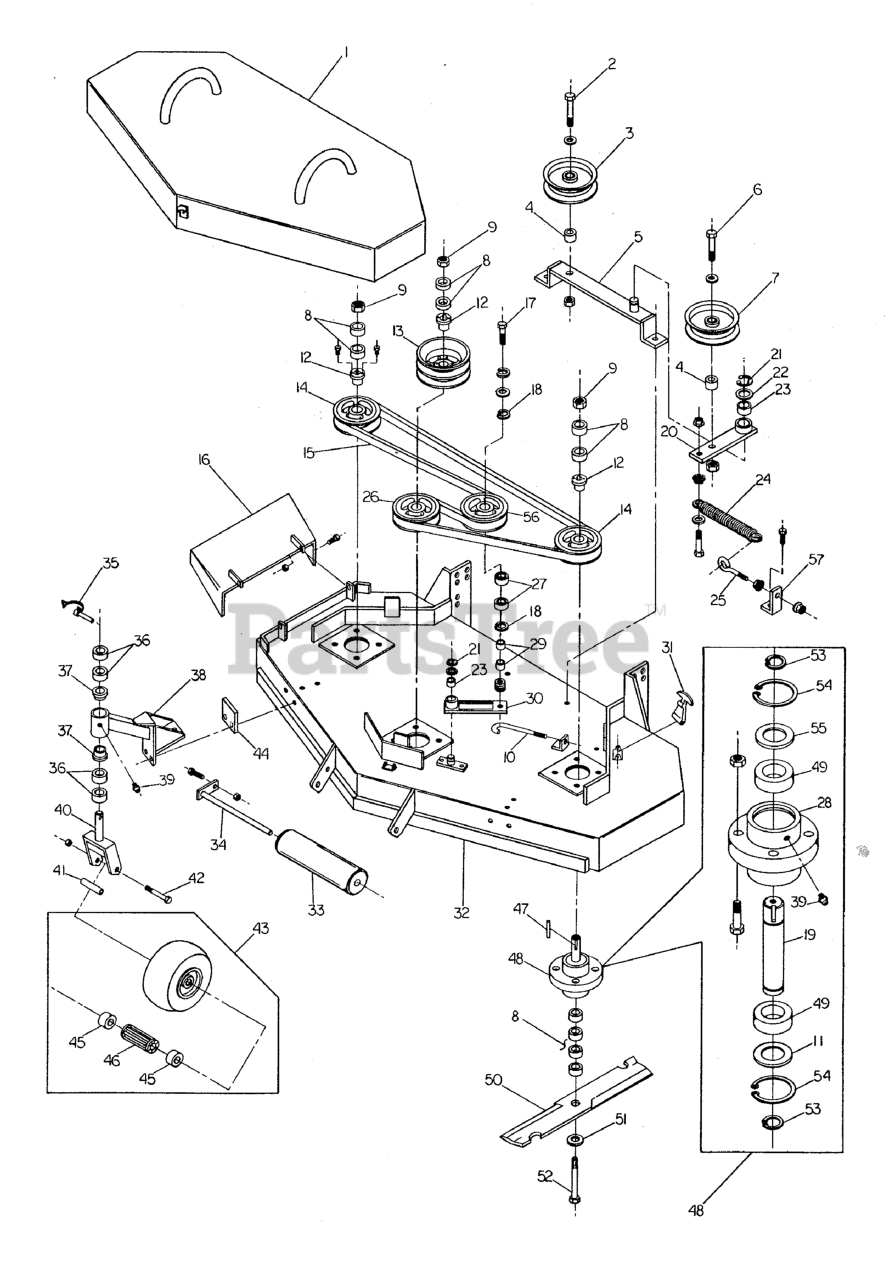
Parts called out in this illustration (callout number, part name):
1	61" DECK GUARD
1	48" DECK GUARD
2	1/2-13 x 3-1/2" Bolt
3	PULLEY, Backside Idler
4	SPACER, .50 x 1.00 X .69
5	Idler Mount
6	1/2-13 x 3" Bolt
7	PULLEY-IDLER-V, 4.85OB, .506 ID, ,94W, STL
8	SPACER, .63 x 1.06 x .23
9	NUT, Hex, 5/8-11
11	SPINDLE WASHER, Bottom
12	BUSHING, Tapered Hub
13	Double Pulley
14	PULLEY, Spindle
15	BELT, Blade Spindle
16	CHUTE, DISCHARGE WELDMENT
17	1/2-20 x 2 1/4" Bolt
18	SNAP RING, Internal
19	Shaft, Spindle
20	Ann, Idler w/ Bushing
20	Arm, Idler w/ Bushing
21	C-CLIP, 3/4" SHAFT
22	SHIM
23	BUSHING, BRASS, 3/4 X 1 X 1
24	SPRING-EXT, .750OD X 7.65LG X .115WR
25	EYEBOLT
26	SPINDLE PULLEY
27	BEARING, BALL 11/16X1-9/16X15/32
28	Housing, Spindle
29	INSERT, Bearing
30	IDLER ARM
31	Latch, Rubber
32	61" MOWER HOUSING (4 Bolt)
32	48" MOWER HOUSING
33	ROLLER, DECK
35	PIN, LYNCH, 7/16"
36	SPACER, 1.02 x 1.56 x .50
37	BUSHING, Flange
38	Caster Support
39	GREASE FITTING, 1/4-28 Straight
40	YOKE, Caster
41	AXLE, Caster Wheel
42	1/2-13 x 5-1/2" Bolt
43	Caster Assembly
44	Caster Mount Spacer
45	RETAINER, BEARING (TWO PER TIRE)(SV)
46	BEARING, ROLLER 3/4" ID X 3.25" (ONE PER TIRE)(SV)
47	Key, 1/4" Sq. x 2-1/2"
48	SPINDLE ASSEMBLY, Complete
49	BEARING
50	BLADE SET, 61 DECK (SET OF 3 BLADES)
50	BLADE SET, 48 DECK (SET OF 3 BLADES)
51	5/8 Washer
52	Bolt, 5/8-11 x 9-1/2 GD.5 Plain
53	SNAP RING, EXTERNAL, 1 SHAFT
54	SNAP RING, Internal
55	SPINDLE WASHER, Top
56	PULLEY, Idler
57	SPRING ANCHOR
57	Spring Anchor
